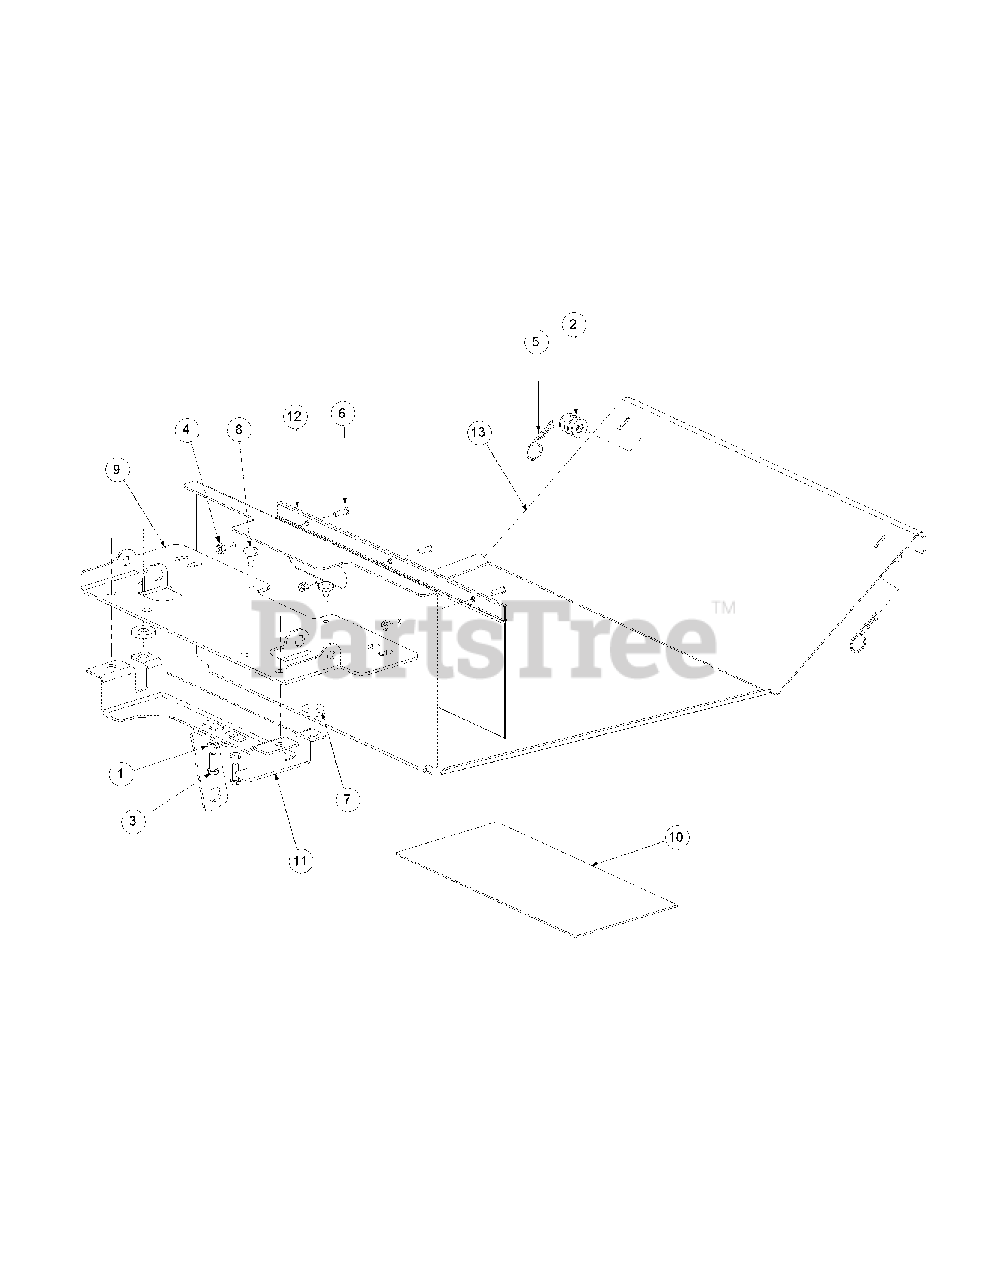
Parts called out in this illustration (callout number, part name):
1	Lock Washer, 1/4
3	Hex Cap Screw, 1/4-20, .75
4	Lock Nut, Nylon Insert, 10-32
5	Hair Pin, 3/8-1/2
6	Screw, Phillips Head, Machine, 10-32 x 5/8
7	Washer
8	Rubber Bumper, .62 OD x .22 Thick
10	Label, Belt Routing and Lubrication
11	Support, Seat Bracket
12	Bag, Debris Storage
13	Floor Panel Assembly
